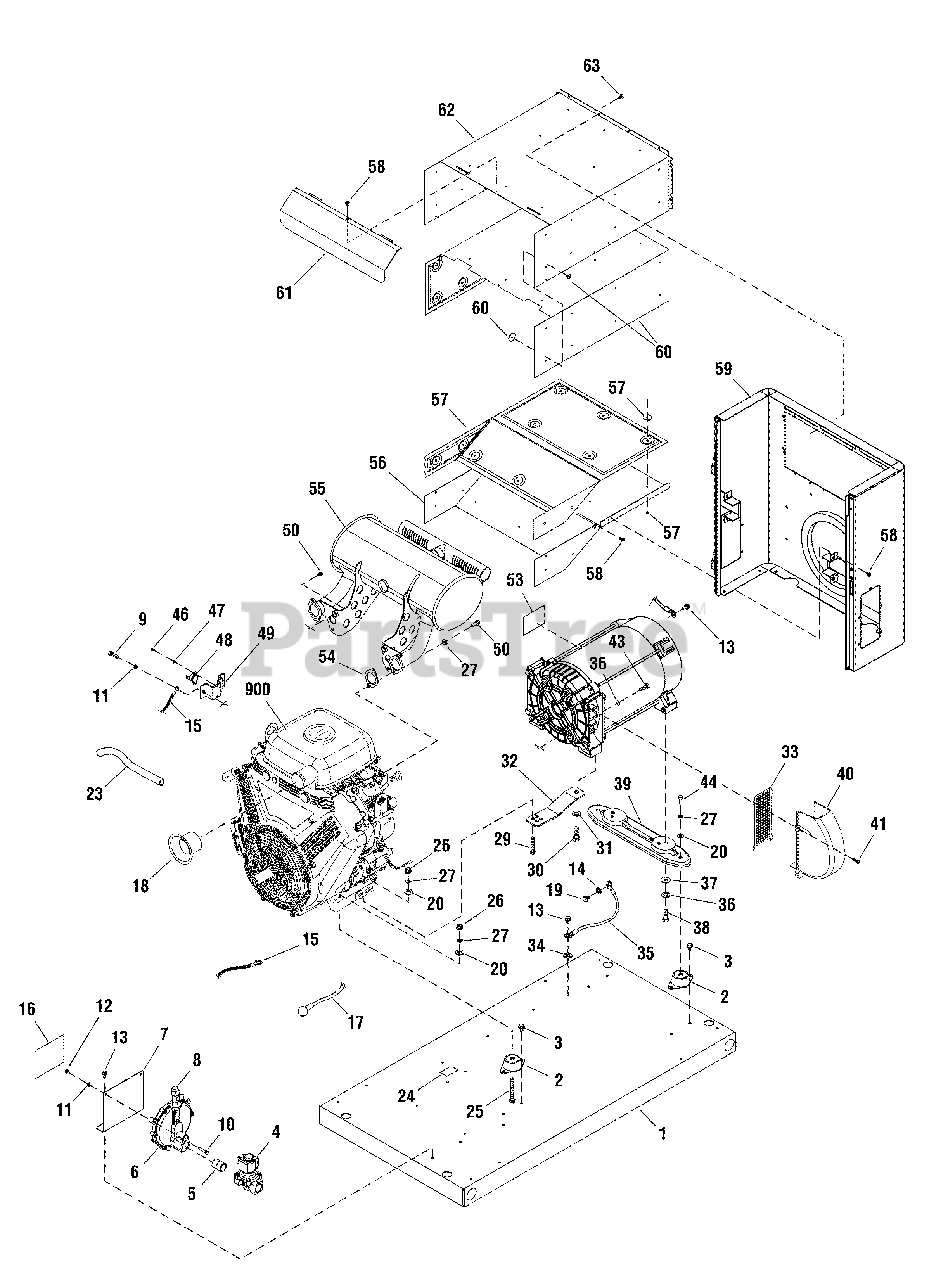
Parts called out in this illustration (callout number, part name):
2	MOUNT, Vibration
4	SOLENOID, Gas Fuel
6	REGULATOR, NG / LPG
9	* CAPSCREW, Hex Head, M6 - 1 x 16
10	* CAPSCREW, Hex Head, M6 - 1 x 30
11	* WASHER, Lock, 1/4
12	* NUT, M6 - 1
13	BOLT
14	* WASHER, Shakeproof, M6
15	CABLE, Battery, Black
16	DECAL, Fuel Requirements
17	CABLE, Battery, Red
20	* WASHER, Flat, 5/16 - M8
23	HOSE, Oil Drain
24	DECAL
25	* CAPSCREW, Hex Head, 5/16-18 x 2-1/2
26	* NUT, 5/16-18
27	* WASHER, Lock, 5/16 - M8
29	* CAPSCREW, Hex Head, 5/16-18 x 2
30	* CAPSCREW, Hex Head, M12 - 1-3/4 x 35
31	* WASHER, M12
32	SUPPORT, Engine
34	* WASHER, Shakeproof, M6 - 1/4
36	* WASHER, Lock, 3/8
37	* WASHER, Flat, 3/8
38	* CAPSCREW, Hex Head, 3/8-16 x 1
39	SUPPORT, Alternator
41	* SCREW, Taptite, M5.8 x 10
43	* CAPSCREW, 3/8-16 x 1-1/4
44	* CAPSCREW, Hex Head, 5/16-18 x 3/4
46	* SCREW, Phillips Head, 4-40 x 0.19
47	* WASHER, Lock, #4
49	PLATE, Temp Switch
50	* CAPSCREW, Hex Head, M8 - 1-1/4 x 25
53	DECAL, Warning, Burn Hazard
59	BULKHEAD, Alternator
62	BOX, Muffler Top
900	** ENGINE
